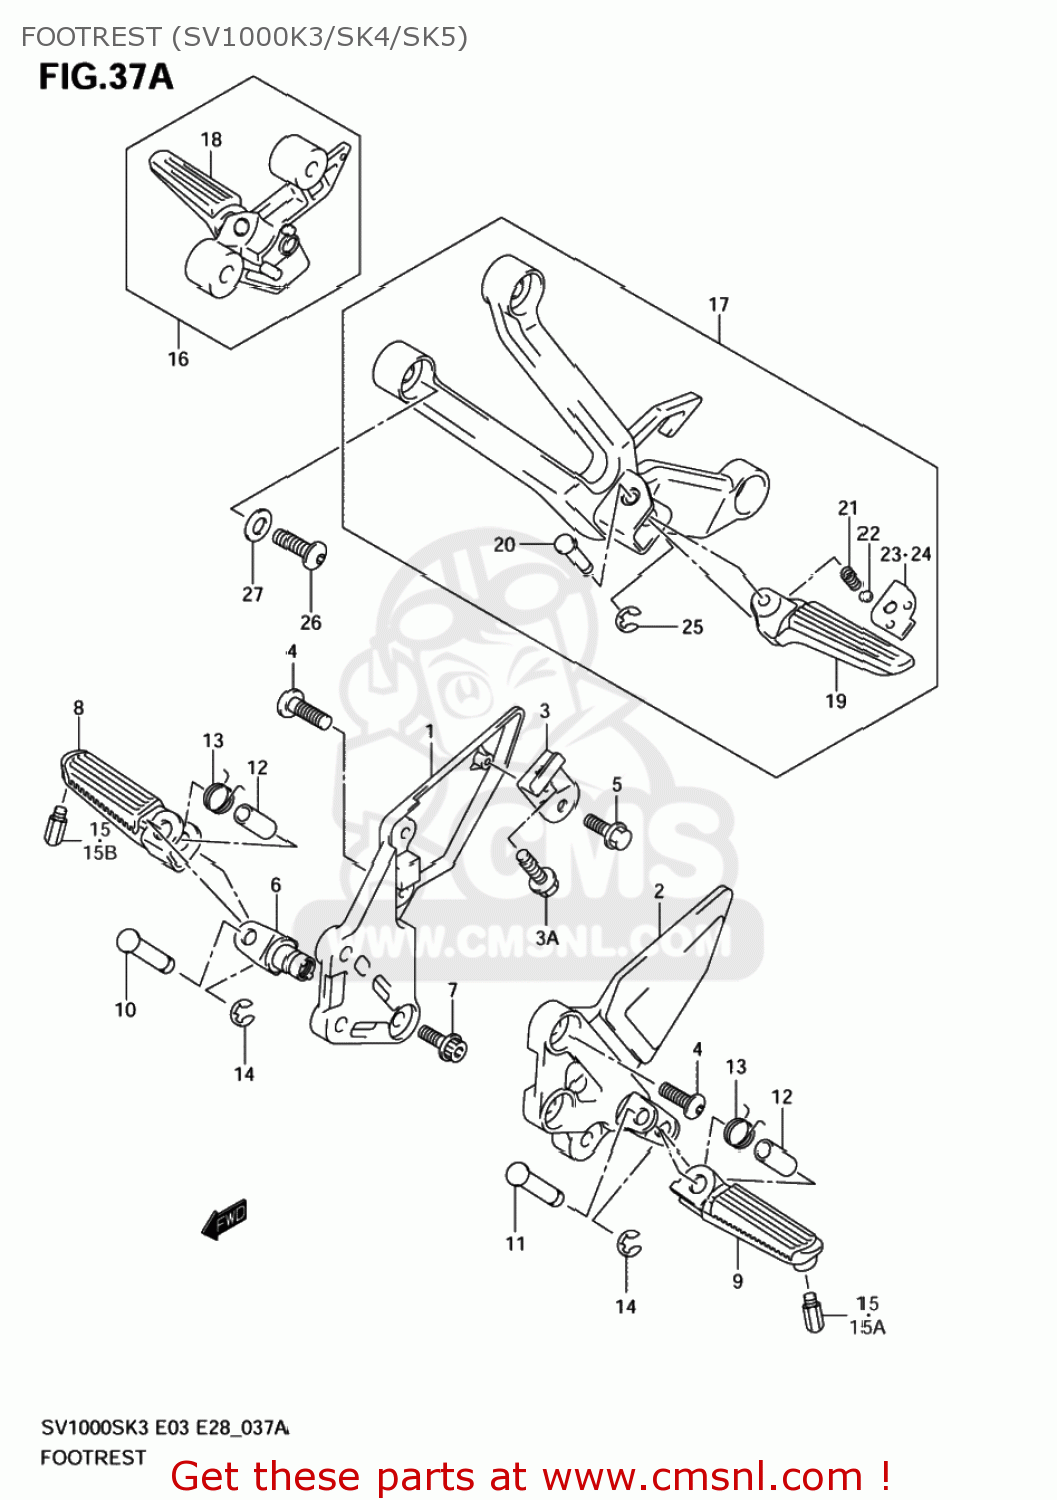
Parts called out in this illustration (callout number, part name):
1	BRACKET,FR FOOTREST,R
2	BRACKET,FR FOOTREST,L
3	REINF,FOOTREST BRACKET
3A	BOLT
4	BOLT 8X20
5	BOLT
6	HOLDER,FOOTREST,R
7	BOLT(10X28)
8	BAR,FR FOOTREST,R
9	BAR,FR FOOTREST,L
10	PIN
11	PIN
12	SPACER(8.1X12X22)
13	SPRING
14	E.RING
15	BOLT,BANK SENSOR
15A	BOLT,BANK SENSOR
15B	BOLT,BANK SENSOR
16	FOOTREST ASSY,PILLION,R
17	FOOTREST ASSY,PILLION,L
18	BAR,PILLION FOOTREST,R
19	BAR,PILLION FOOTREST,L
20	PIN
21	SPRING
22	BALL
23	PLATE,PILLION FOOT,R
24	PLATE,PILLION FOOT,L
25	E-RING
26	BOLT(8X23)
27	WASHER
